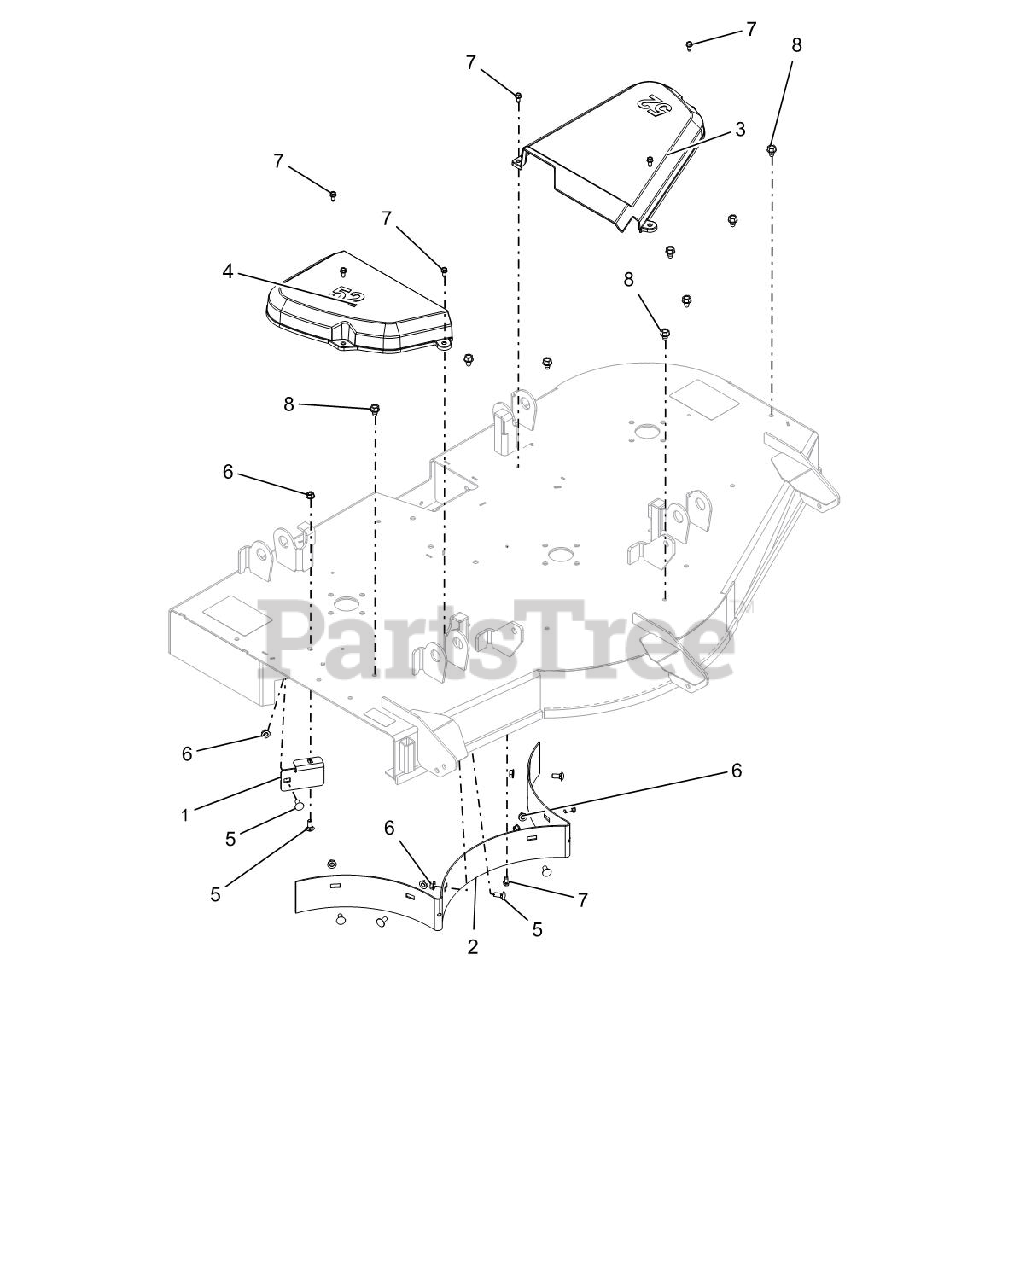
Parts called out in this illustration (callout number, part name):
1	STRIP, DEFLECTOR - 52"
2	BAFFLE, REAR - REMOVABLE 52"
3	COVER, BELT 52" LH
4	COVER, BELT 52" RIGHT
5	@BLT-RDHDSQNK .31-18X.75 G5YZ
6	@NUT-LK-TOP-FLG .31-18 YWZC
7	SCR-TAP .25-20X.50 HWH TR YWZ
8	@SCR-TAP .38-16X.50 HWH TR YWZ
